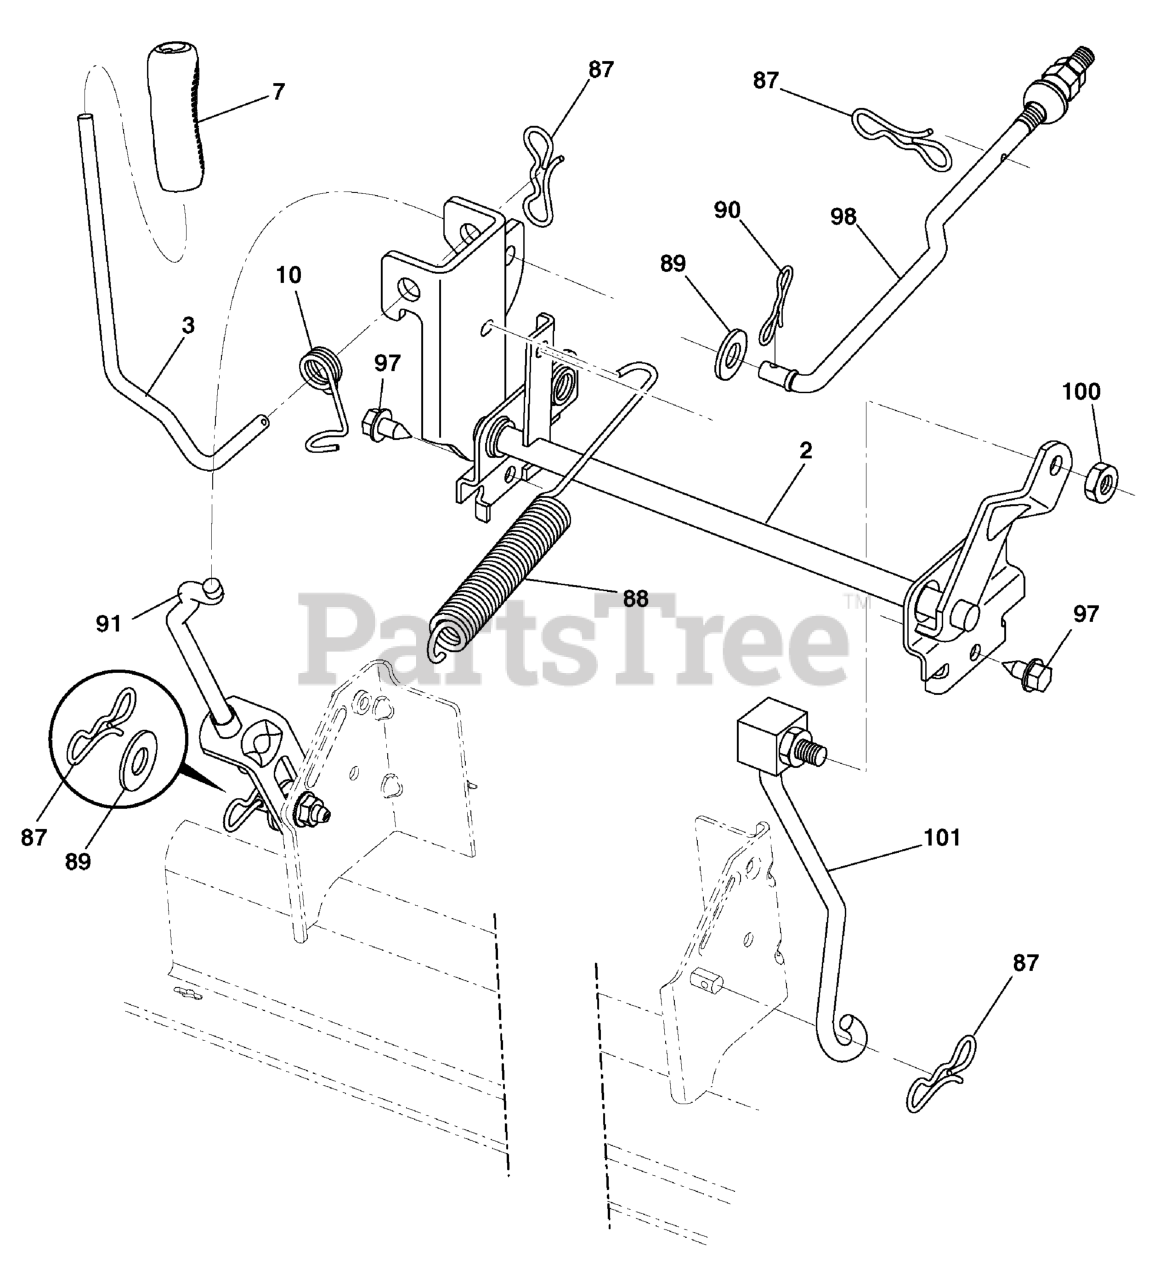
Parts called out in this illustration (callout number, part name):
2	Shaft Asm., Lift
3	Lever Asm., Lift RH
7	Grip, Lever
10	Spring Torsion
87	Pin Cotter 7/16 Bow Tie Lock
88	Spring Lift Assist
89	Washer Clear Zinc
90	Pin Cotter 5/16 Bow Tie Lock
91	Link Lift Susp Mower Rear
97	Screw 3/8-16 x .75 Smgml Tap/R.Z
98	Link Lift Susp. Front Mower
100	Nut Lock 3/8-16 unc
101	Link Asm Lift FXD
